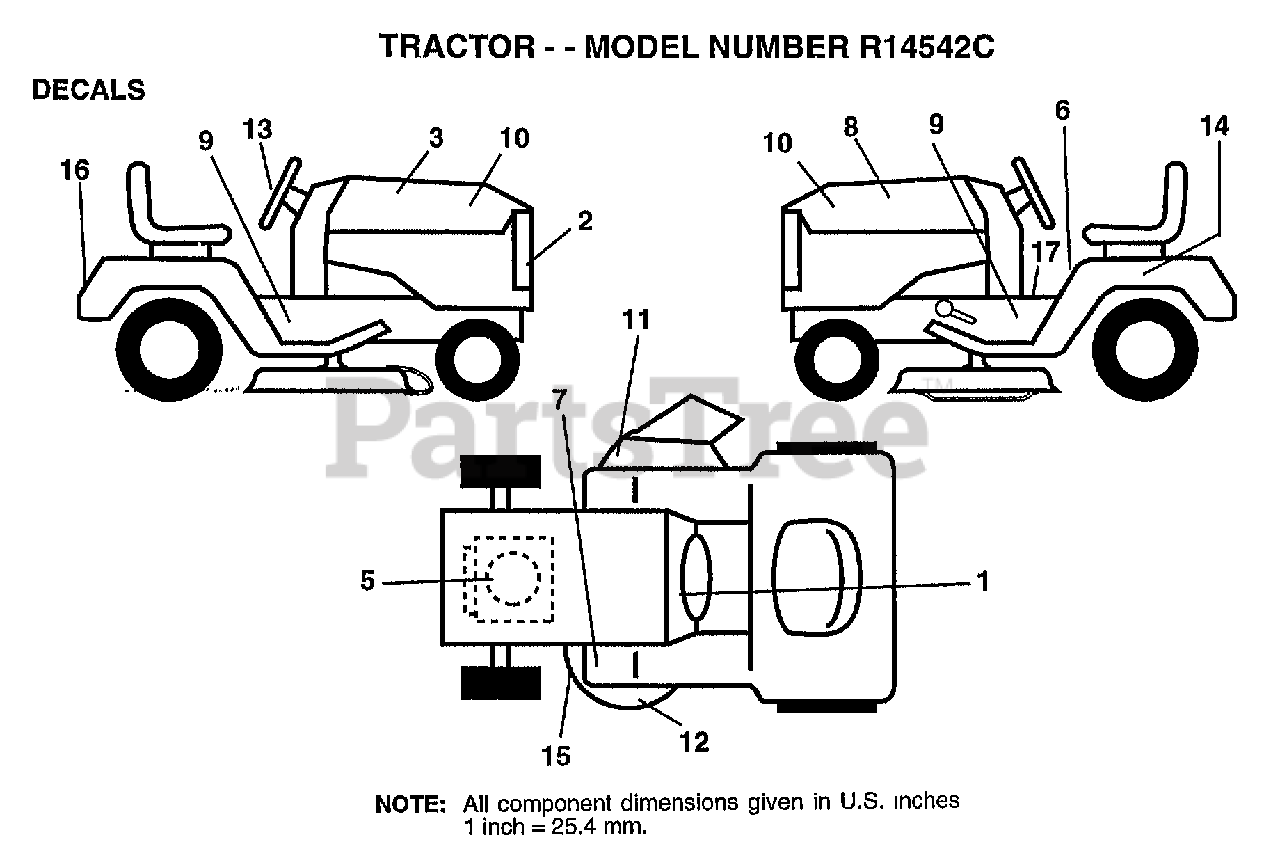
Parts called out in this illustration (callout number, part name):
1	DECAL.INSTR.FRENC
2	GRILL DECAL
3	DECAL.HD.RH.RALLY
5	DECAL, ENGINE
6	DECAL.CAUT.ENG/FR
7	DECAL T
8	DECAL.HD.LH.RALLY
9	CHASSIS DECAL
10	DECAL.INS.HD.RALL
11	"DECAL, WARNING"
13	"DECAL,STR WHL"
14	DECAL.BATRY.3-3908
15	"DECAL-SCHEM,BELT"
16	FENDER DECAL
17	DECAL BRAK PARK
